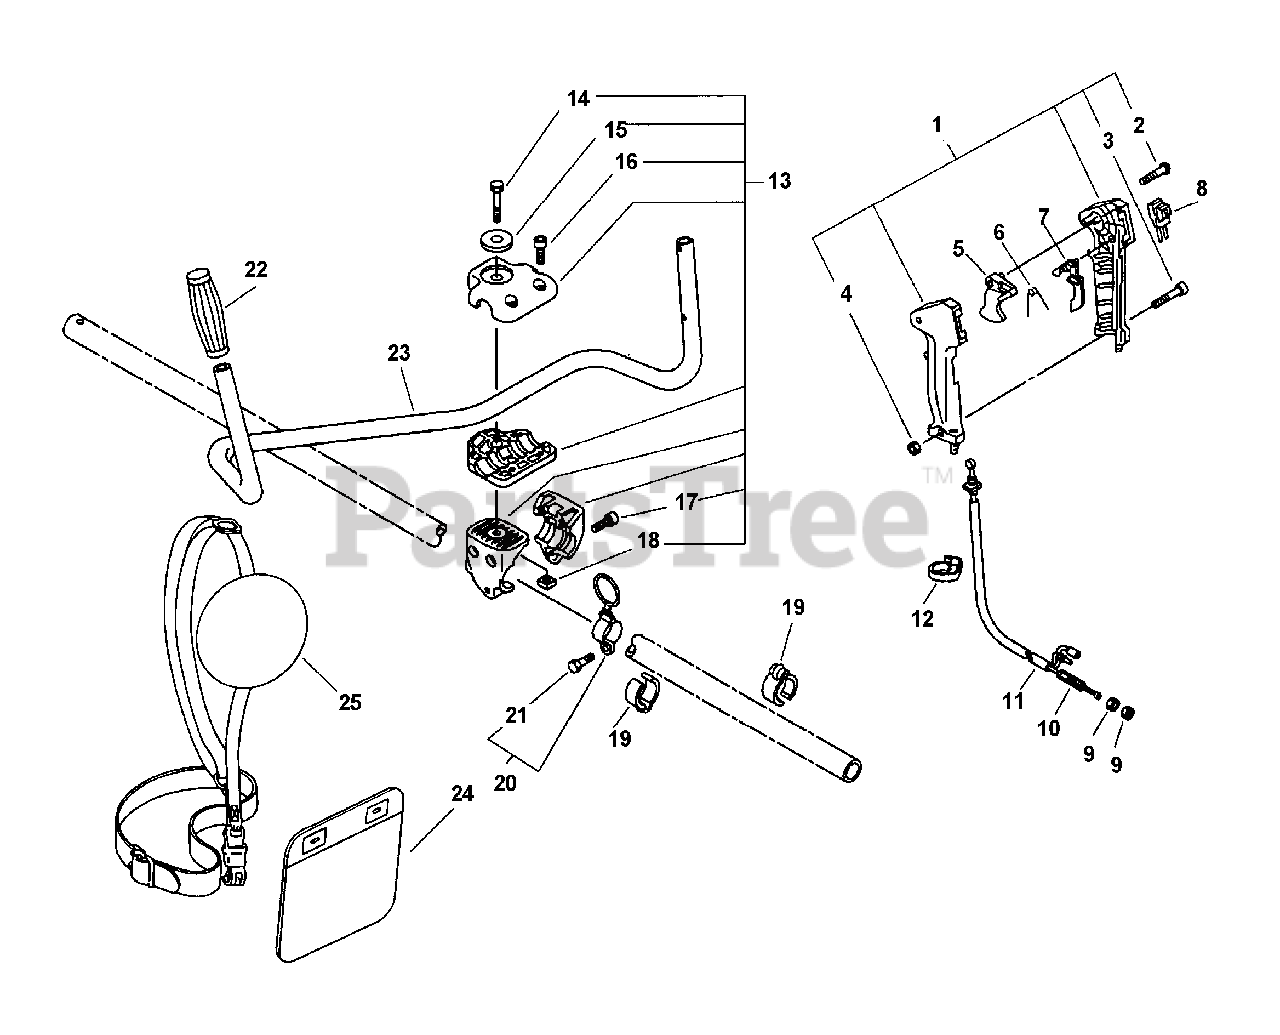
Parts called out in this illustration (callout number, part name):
1	THROTTLE CONTROL ASSY
2	SCREW - 3X25
3	SCREW - 5X30
5	TRIGGER, THROTTLE
6	SPRING, LOCKOUT LEVER
7	LOCKOUT, THROTTLE
8	IGNITION SWITCH ASSY
9	NUT - 6
10	CABLE, THROTTLE
11	TUBE, PROTECTIVE - CORRUGATED
13	HANDLE BRACKET KIT
14	BOLT - 8X55
15	WASHER - 8
16	SCREW - 5X20
17	SCREW - 5X30
20	HANGER KIT
21	BOLT - 5X12
22	GRIP, HANDLE - LEFT
23	HANDLE - FRONT
24	CUSHION
25	SHOULDER STRAP ASSY
